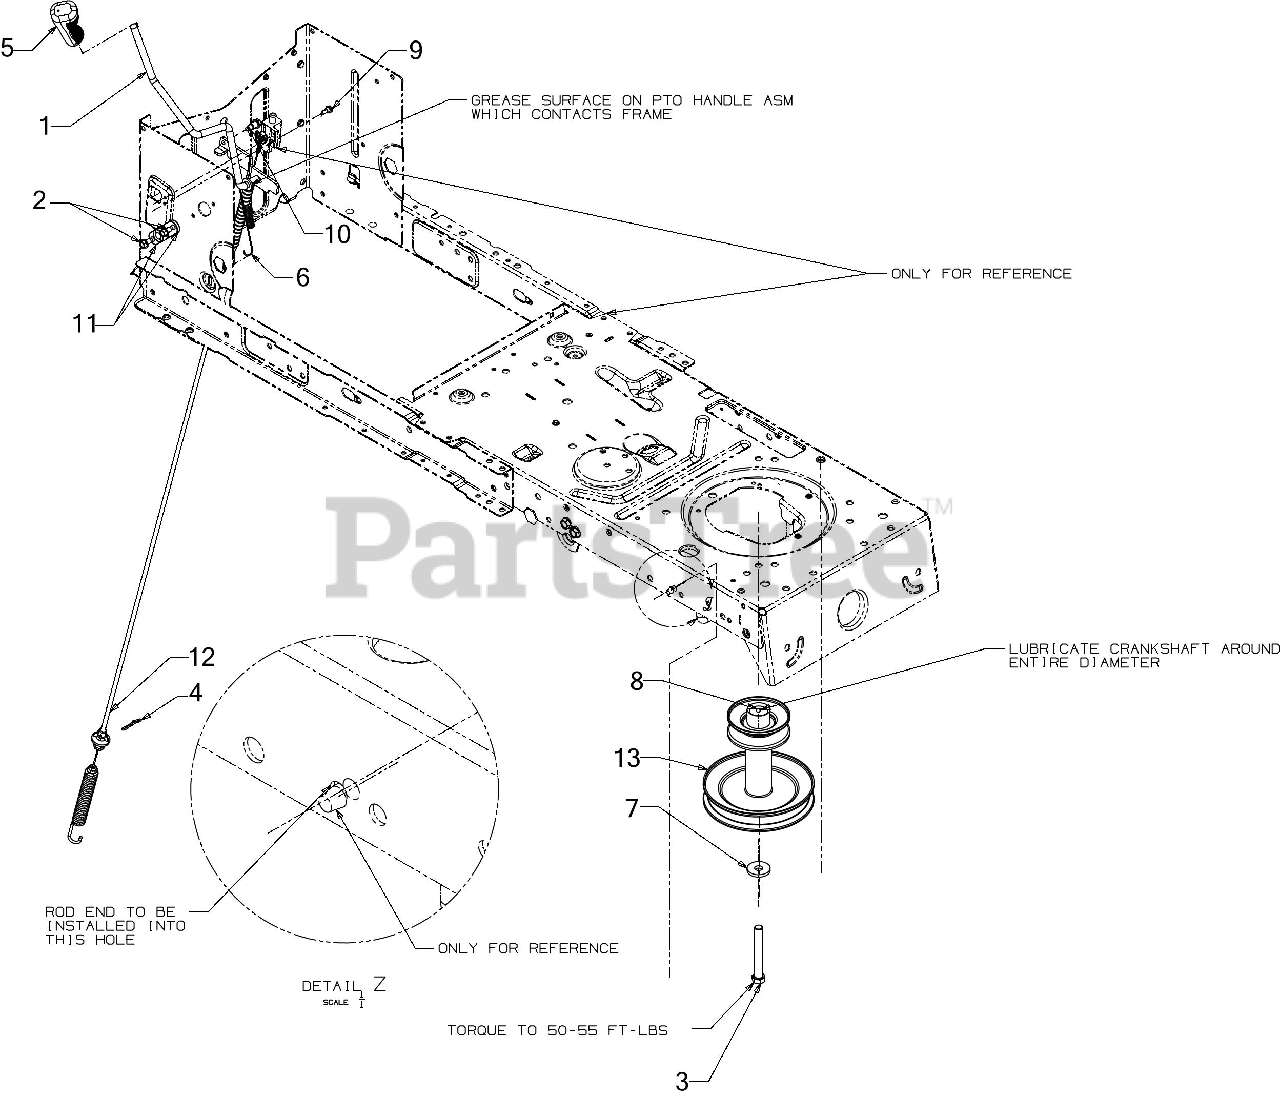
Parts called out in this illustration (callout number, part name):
1	PTO HANDLE ASSEMBLY
2	SCREW 1/4-20 X.500
3	SCREW 7/16-20 x 3.25 GR5
4	BOW TIE COTTER PIN 1/4-5/16
5	HANDLE GRIP
6	EXTENSION SPRING
7	FLAT WASHER .445 x 1.248 x .170
8	GREASE (NOT SERVICEABLE)
9	SHOULDER SCREW
10	SHOULDER SCREW
11	PTO BEARING
12	DECK ENGAGEMENT CABLE
13	ENGINE PULLEY 3.39 x 6.12 DIA
